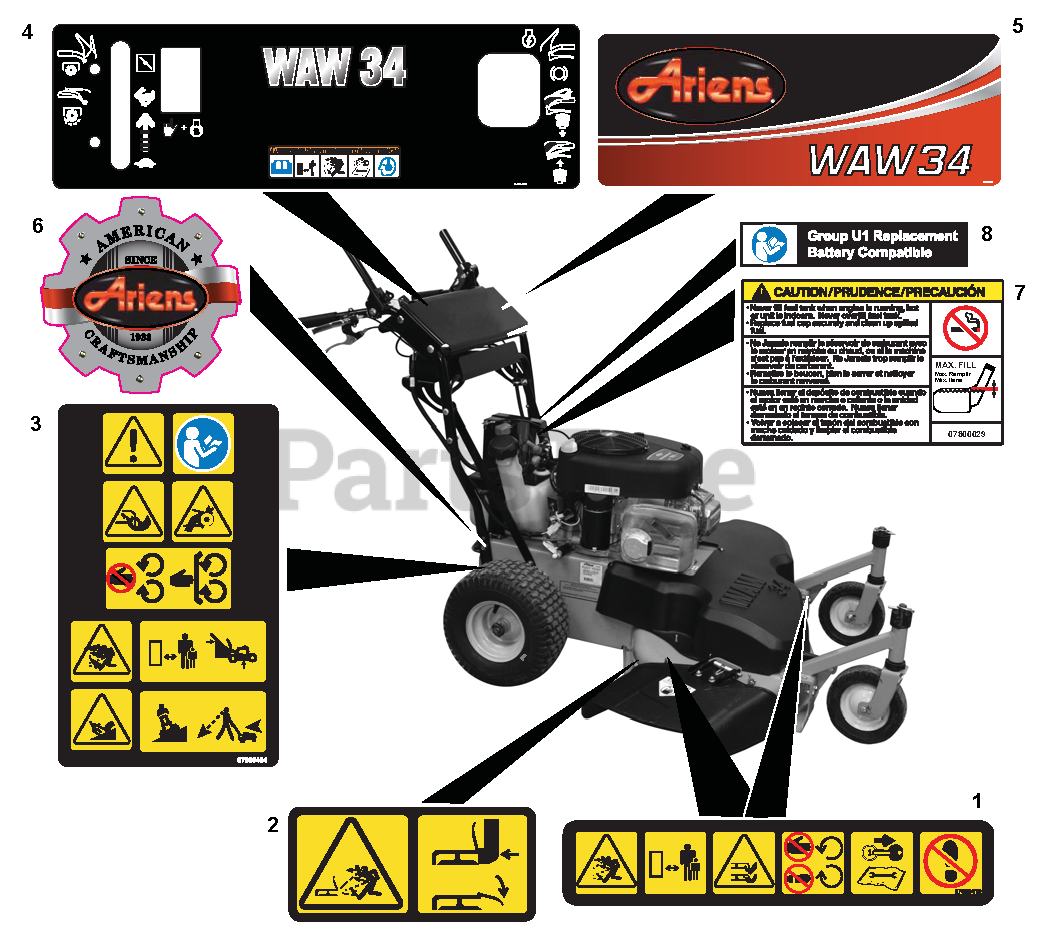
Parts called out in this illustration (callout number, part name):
1	DECAL, DECK SAFETY
2	DECAL, SAFETY - DECK GUARDING
3	DECAL,MAIN SAFETY_WAW LM
4	DECAL, WAW 34 OPERATIONAL
5	DECAL,WAW 34 ARIENS DASH
6	Decal, Ariens Heritage
7	DECAL-FUEL, WARNING
8	DECAL, U1 BATTERY REPLACEMENT
